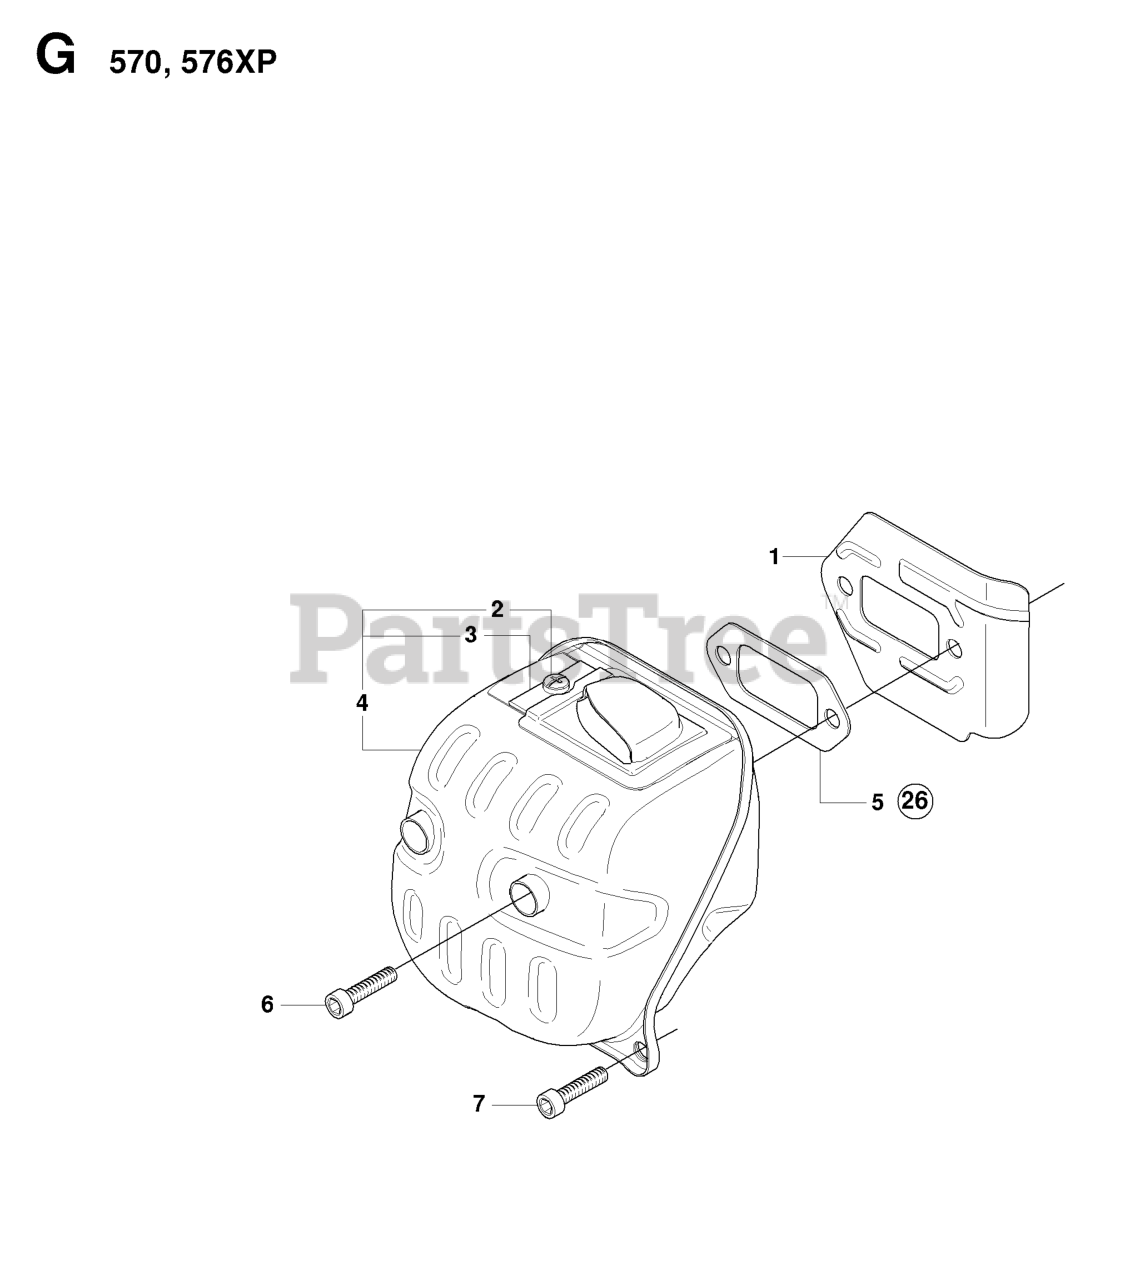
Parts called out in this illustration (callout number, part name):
4	MUFFLER ASSY (DF US)
4	MUFFLER ASSY (FF CE)
6	SCREW MC6S 6X20
26	GASKET KIT
26	GASKET SET
